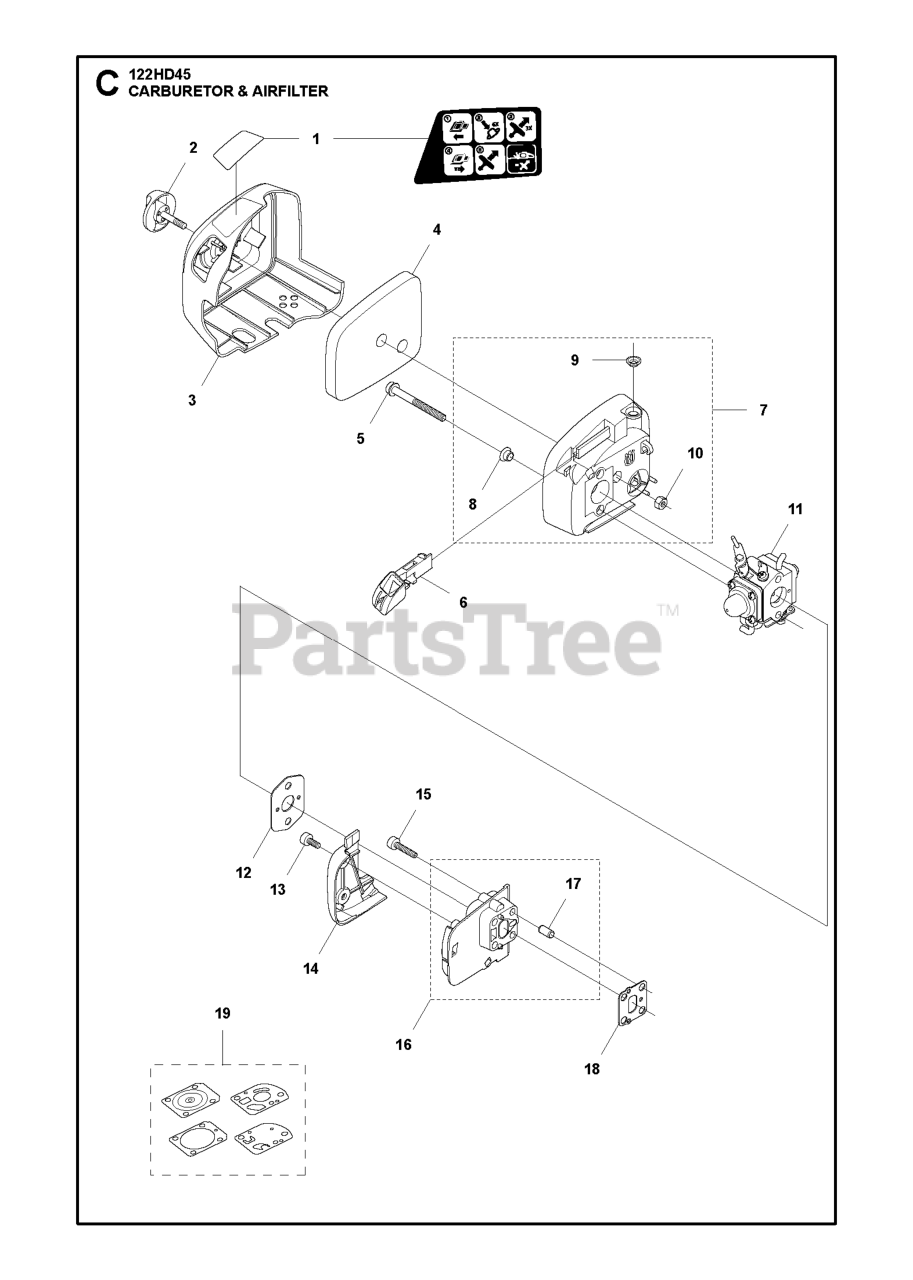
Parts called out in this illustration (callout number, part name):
4	VALVE
8	VALVE
10	SPACING SLEEVE
11	Carburetor Assembly
12	RETAINING RING
